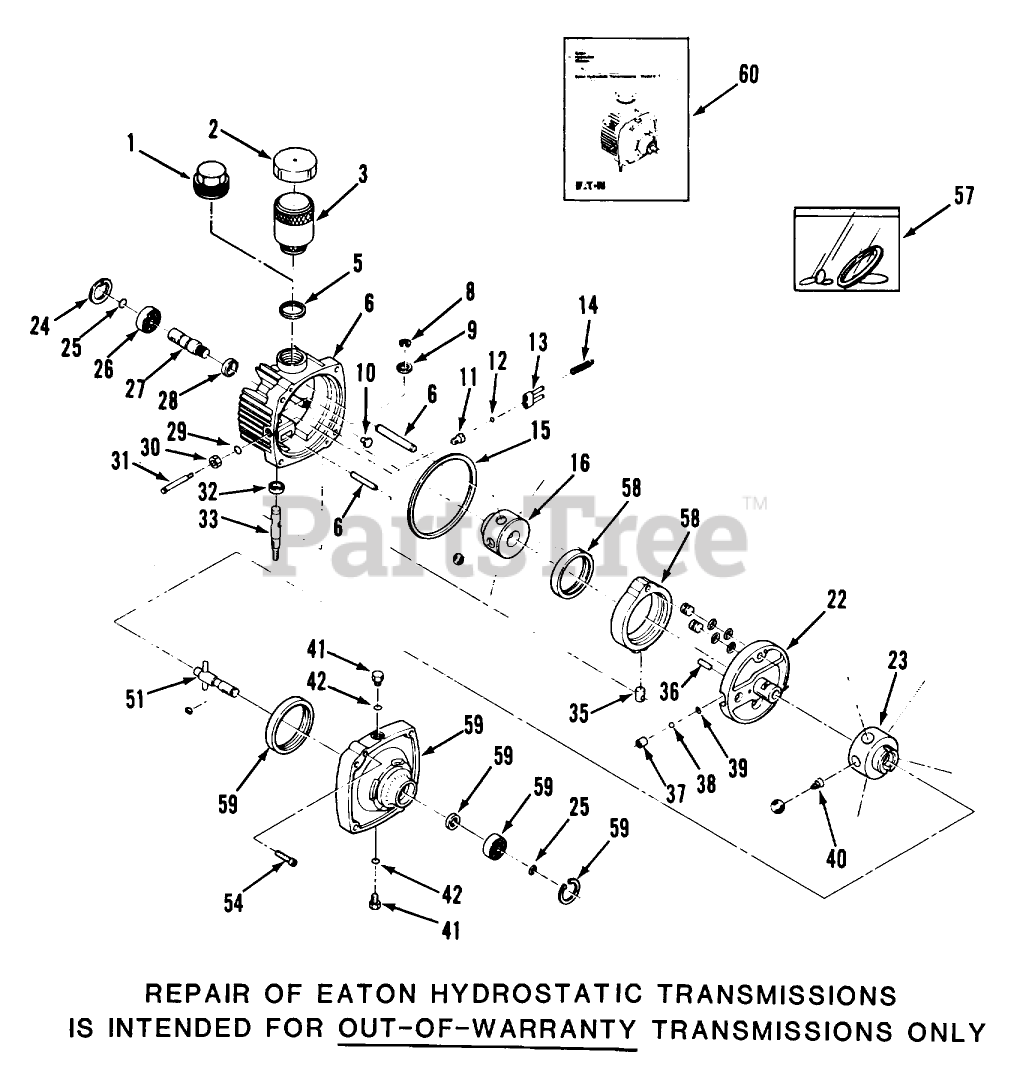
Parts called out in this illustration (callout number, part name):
2	RESERVOIR COVER
3	BODY-RESERVOIR
5	SEAL-RING SQUARE CUT
14	SPRING-VALVE
16	SUB-ASS'Y PUMP ROTOR
25	SNAP-RING
26	BEARING-BALL (INPUT)
27	SHAFT-INPUT
32	SEAL-OIL
57	KIT-OVERHAUL SEALING
59	SUB-ASS'Y BODY
60	Hydrostatic Transmission Repair Manual
